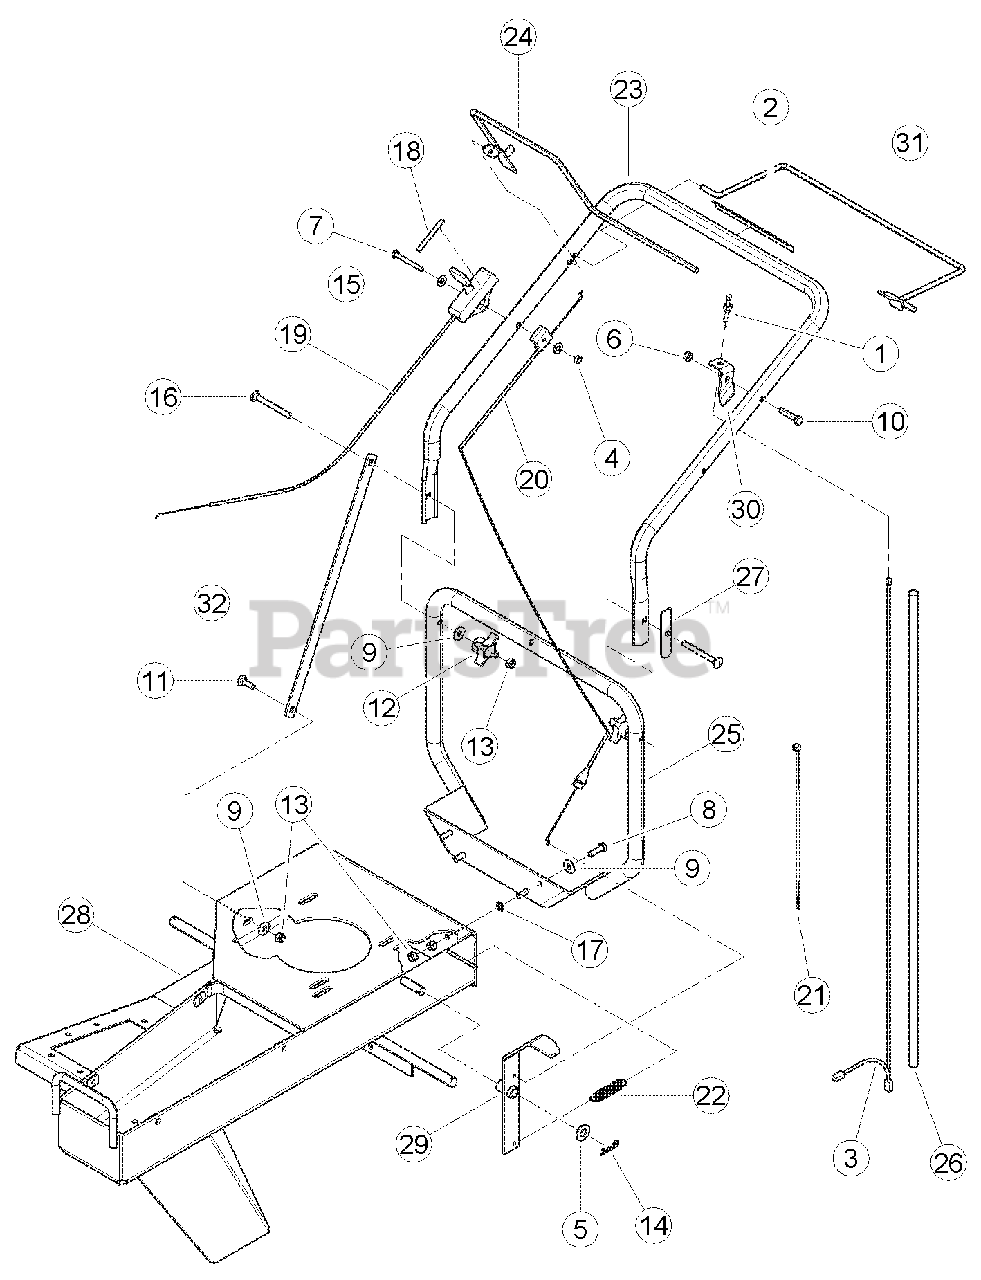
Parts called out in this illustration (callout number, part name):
1	SWITCH, ENGINE KILL
2	DECAL, STUMPGRINDER CONTROL
3	WIRE ASSY, ENGINE KILL
4	NUT, 1/4 CENTERLOCK NC ZP
5	WASHER, 1/2 SAE FLAT ZP
6	NUT, 5/16 CENTERLOCK NC ZP
7	BOLT, 1/4 X 2-1/4 HCS GR5 ZP
8	BOLT, 5/16 X 1 HHCS GR5 NC ZP
9	WASHER, 5/16 FLAT ZP
10	BOLT, 5/16 X 1-1/2 HEX HD GR5 ZP
11	BOLT, 5/16 X 1 CRG GR5 ZP
12	KNOB, SPOUT 5/16-18
13	NUT, 5/16 NE NYLOCK ZP
14	HAIRPIN CLIP ZP #203
15	WASHER, 5/16 SAE FLAT ZP
16	BOLT, 5/16 X 3 CRG GR5 NC ZP
17	WASHER, 5/16 EXTERNAL TOOTH ZP
18	DECAL, THROTTLE
19	THROTTLE CONTROL
20	CABLE, STUMP GRINDER
21	STRAP, 11 IN. BLACK TIE
22	SPRING, LT EXT .555OD X 2.75LG
23	UPPER HANDLE BAR
24	TOP BALE WELDMENT
25	WELDMENT, HANDLEBAR
26	CONDUIT, 1/4 X 47 WIRE
27	BRACE, HANDLEBAR
28	WELDMENT, STUMPGRINDER FRAME
29	WELDMENT, WHEEL BRAKE
30	STRIP, SWITCH MOUNT
31	WELDMENT, BOTTOM BALE
32	STRIP, HANDLEBAR SUPPORT
